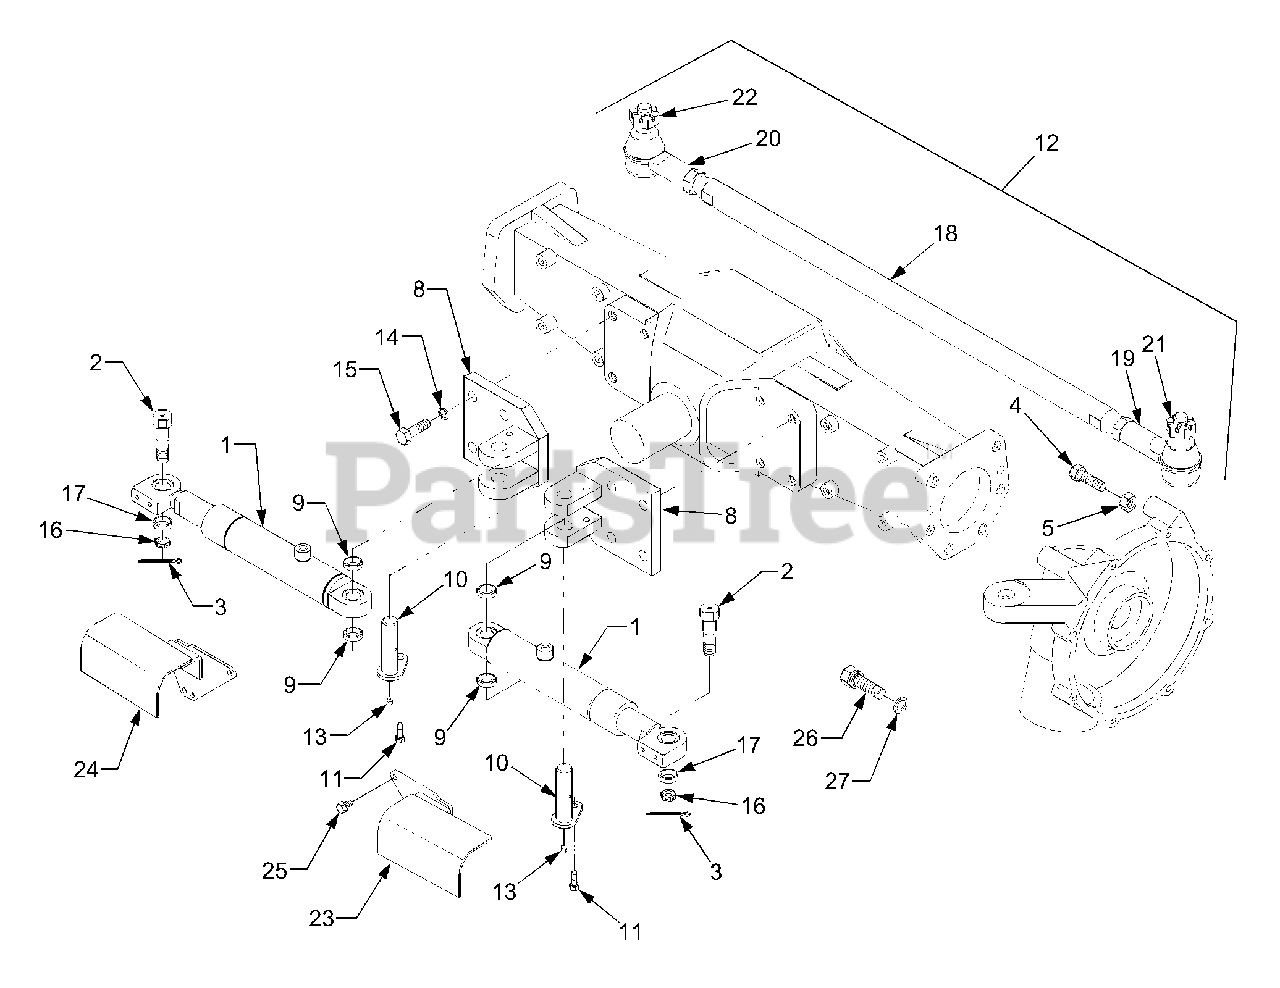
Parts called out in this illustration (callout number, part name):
1	Steering Cylinder Ass'y
2	Pin, Support
6	Support, Cylinder
12	Tie Rod Ass'y
14	Washer, Spring
18	Rod, Tie
19	Tie Rod End Ass'y (LH)
20	Tie Rod End Ass'y (RH)
23	Cover, Cylinder (LH)
24	Cover, Cylinder (RH)
27	Washer, Spring
